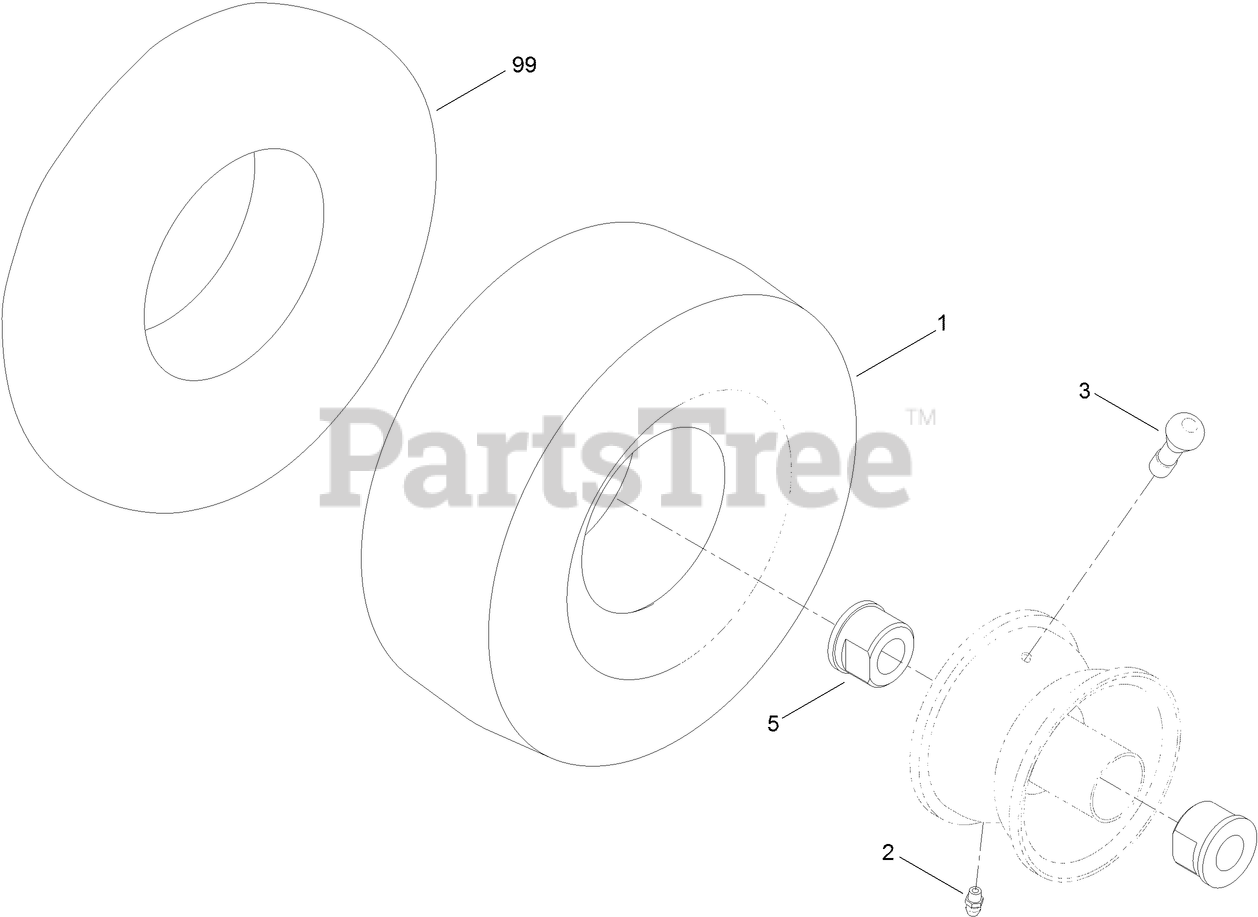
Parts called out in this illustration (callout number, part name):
1	TIRE-SMOOTH (CST)
2	FITTING-GREASE
5	BUSHING-FLANGE
99	TUBE-INNER (W/VALVE)
